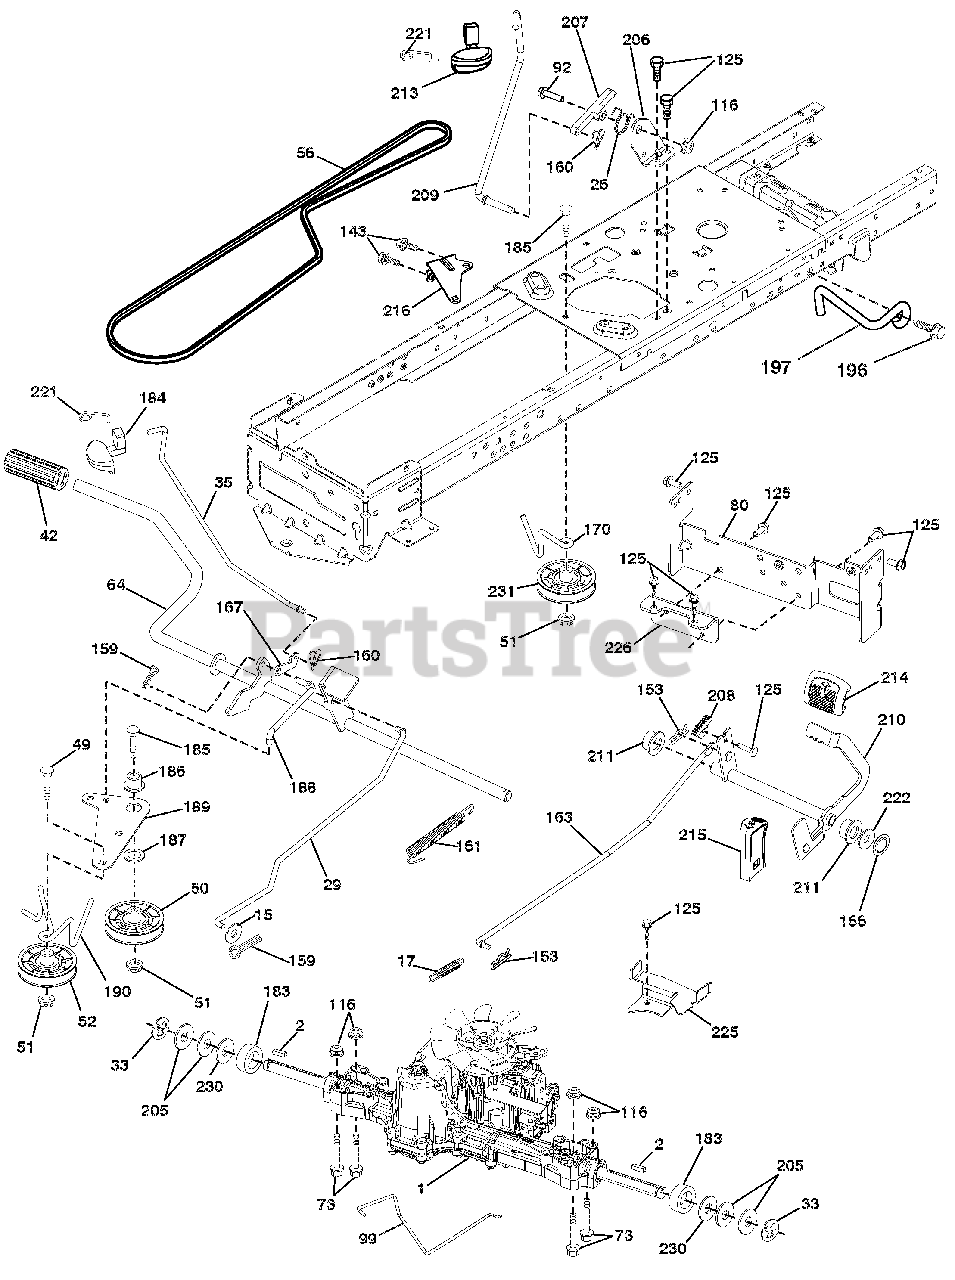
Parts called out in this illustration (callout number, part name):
1	Transaxle, Tufftorq K46BT (Order Parts From Transaxle Manufacturer)
2	KEY.SQUARE.2.0 X .1845/.1865
15	WASHER.13/32 X 13/16 X 16 GA.
17	SPRING.BRAKE.K46.GREEN
26	SPRING.RETURN.CRUISE
29	ROD.BRAKE.K46
33	E-RING.#5133-75
35	ROD.BRAKE.PARKING.LT.TEX
42	COVER.PEDAL.BLK.ROUND
49	BOLT.RDHD.3/8-16UNCX1-3/4.GR5
50	IDLER.FLAT.910"OFFSET
51	Nut, Hex, Flangelock 3/8-16
52	IDLER.V-GROOVE.910"OFFSET
56	V-BELT.MOWER.92.40.42/K46
64	SHAFT ASM.PEDAL.BRK.CNTRL.PCH
73	BOLT.HEX.FLGHD.5/16-18.GR.5
80	STRAP.TORQUE.K46/18"TEX
92	Bolt, Hex Head 5/16-18 x 1-1/4
99	ROD.SPRING.BYPASS.K46.LT.Z
116	Nut, Lock Hex Flange 5/16-18 u
125	SCREW.5/16-18X3/4.SMGML.TAP/BL
143	SCREW.THDROL.5/16-18 X 1/2TYTT
153	Retainer Spring
159	PIN.COTTER.1/8 X 3/4.CAD.
160	RETAINER.CLIP(M).DIA.290
161	SPRING.RETURN.CLUTCH.6.75
163	ROD.CONTROL.PEDAL.K46
166	NUT.PUSH..625.2006
167	LATCH.BRAKE.PARKING
170	KEEPER.CENTER SPAN.1.688
183	SPACER.AXLE.HYDRO/PEERLES
184	HANDLE.PARKING BRAKE.LTTEX.505
185	BOLT.RDHD.3/8-16UNC X2-3/4 GR5
186	SPACER.RETAINER
187	WASHER.13/32 X 2 X 10 GA.
188	LINK.CLUTCH.GROUND DRIVE
189	BELLCRANK.GROUNDRIVE.NSTG/NSTL
190	KEEPER.BELLCRANK.DRIVE.GROUND
196	SCREW.3/8-16X1.SMGML.TAP/R.BLK
197	LINK.CLUTCH.ANTI-ROTATIN.1"CRK
205	WASHER.25/32 X 1-5/8 X 16GA.
206	BRACKET.MOUNT.LATCH.CRUISE
207	LATCH.CONTROL.CRUISE
208	GEAR SECTOR.CONTROL.CRUISE
209	ROD.CONTROL.CRUISE.LT.ELITE
210	ROCKER ASM.PEDAL CONTROL.TEXLT
211	BEARING.NYLON.BLK..629 ID.
213	HANDLE.CONTROL.CRUISE.ELTE.428
214	PEDAL.FORWARD.TEX.GT.428
215	PEDAL.REVERSE.TEX.GT.428
216	BRACKET.PULLEY.IDLER.WTEX
221	RETAINER.SPRING.CLIP.HANDLE
222	WASHER.21/32X1-1/4.10GA.N/PLTD
225	KEEPER.BELT.TRANSAXLE.K46
226	BRACKET.MOUNT.TORQUE.K46.TLT
230	WASHER.HARDEN..793 X 1.637X060
231	IDLER.V-GROOVE.1.688"OFFSET
